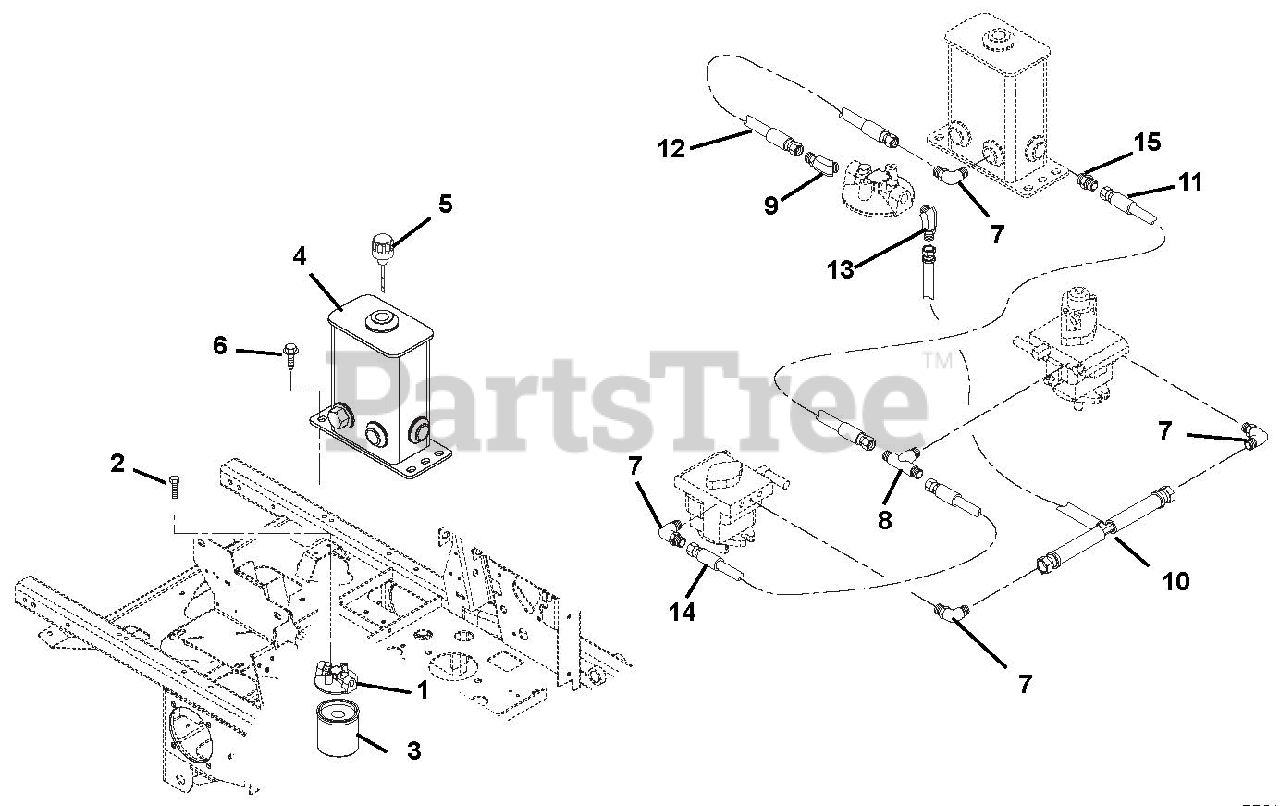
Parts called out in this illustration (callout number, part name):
1	Head, Filter
2	Bolt, Hex .25-20 x .50 Epoxy Grade 5
3	Oil Filter
4	Weldment,Formed Hydraulic Tank-2 PORT
5	Dipstick, Breather
6	Screw, Tapping .38-16 x .75 Hex Washer Head
7	Fitting, Hydraulic, 90 Degree Elbow, Steel M8F-M80
8	Fitting, Hydraulic Tee M80-M80-M80
9	Fitting, Hydraulic Straight M80-M80
10	Hose, Tee Assembly, .50
11	Hose, Hydraulic .50-19-0K FO8J0-FO8J0
12	Hose, Hydraulic Molded
13	Fitting, Hydraulic 45° M80-M80
14	Hose, Hydraulic
15	Adapter, Face Seal 8 x 8 .50 O-Ring 8 F5OLO-Steel
